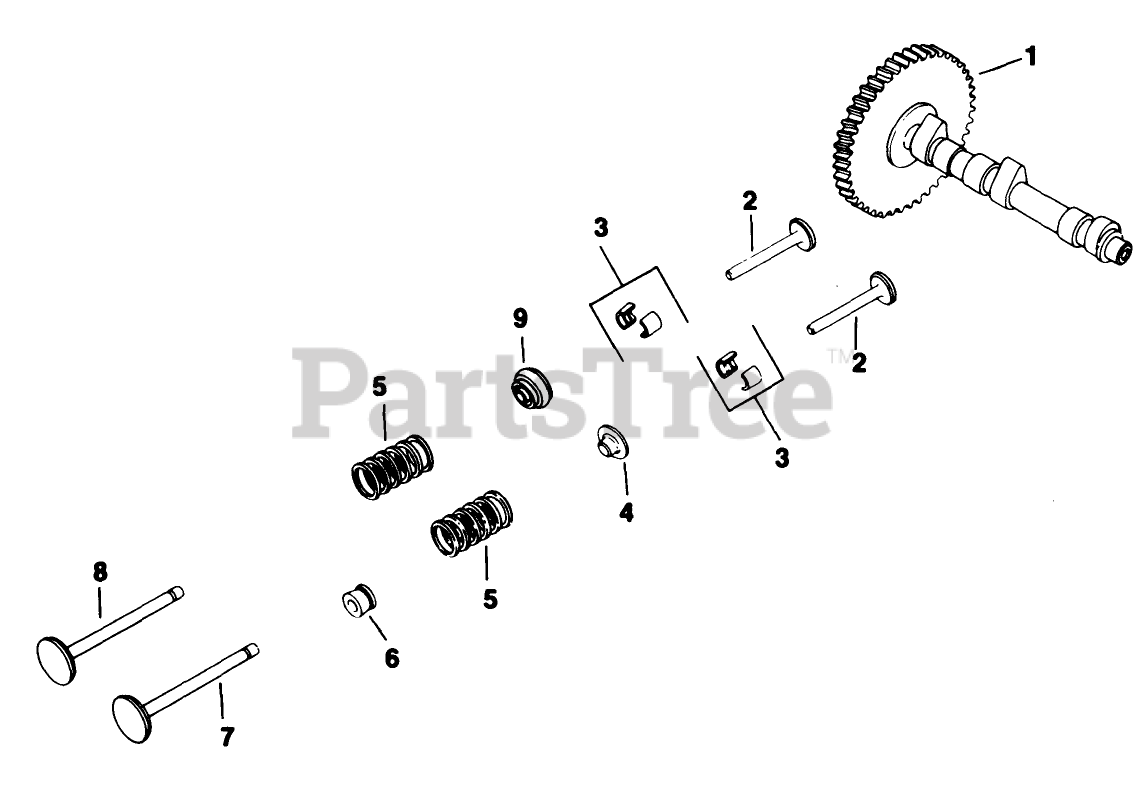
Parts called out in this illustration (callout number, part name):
1	Camshaft
3	Kit-Retainer
4	Retainer-Spring
5	Spring-Valve
6	Seal-Valve Stem
7	Valve-Intake
8	Valve-Exhaust
9	Rotator
